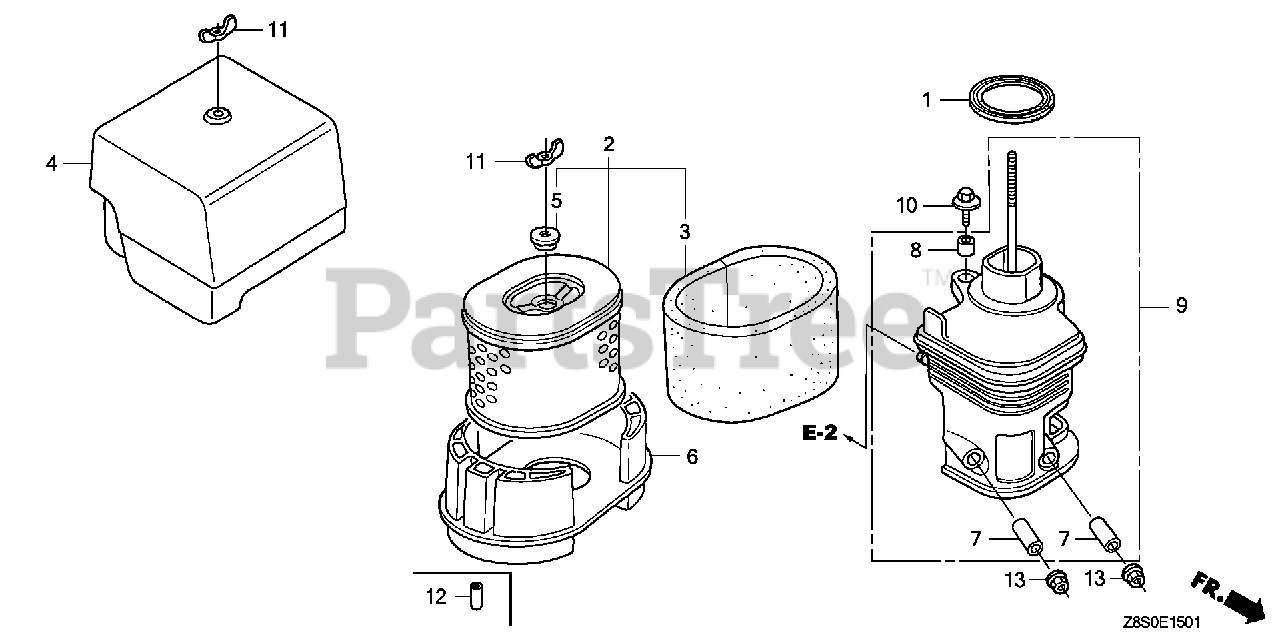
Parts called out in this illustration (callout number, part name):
1	GASKET, ELBOW
2	ELEMENT, AIR CLEANER (DUAL)
3	FILTER (OUTER)
4	COVER, AIR CLEANER
5	GROMMET, AIR CLEANER
6	NOSE, MUFFLER
7	COLLAR, AIR CLEANER
8	COLLAR B, AIR CLEANER
9	ELBOW, AIR CLEANER
9	ELBOW COMP, AIR/C
10	BOLT-WASHER (6X22)
11	NUT, TOOL BOX SETTING
13	NUT, FLANGE (6MM)
